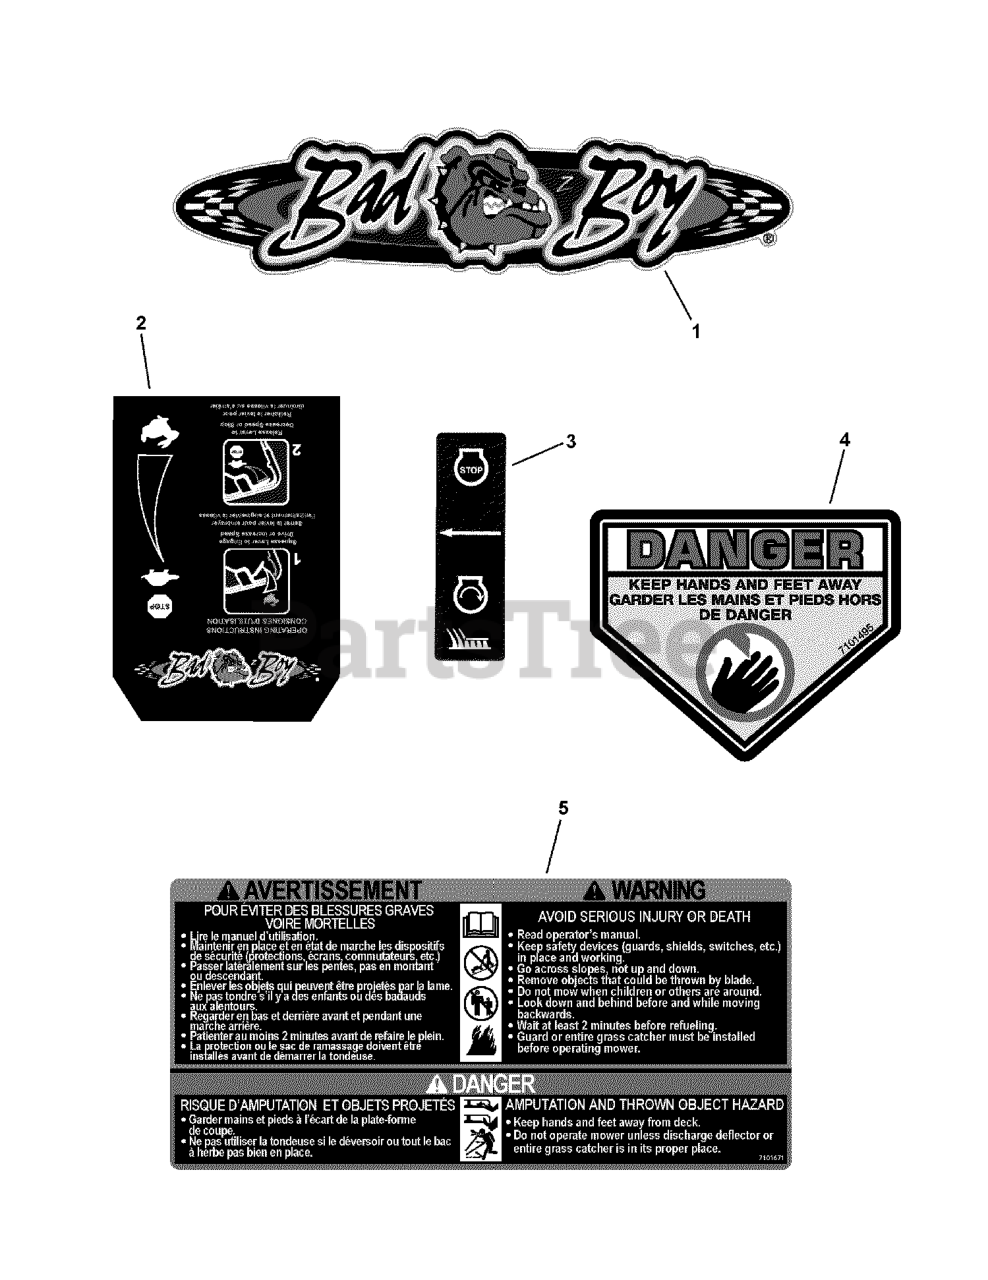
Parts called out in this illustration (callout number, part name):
1	DECAL, Bad-Boy Small
2	DECAL, Controls Bad-Boy
3	DECAL, OPC Bail International Symbol
4	DECAL, CPSC, French/English
5	DECAL, French/English, WB Safety
